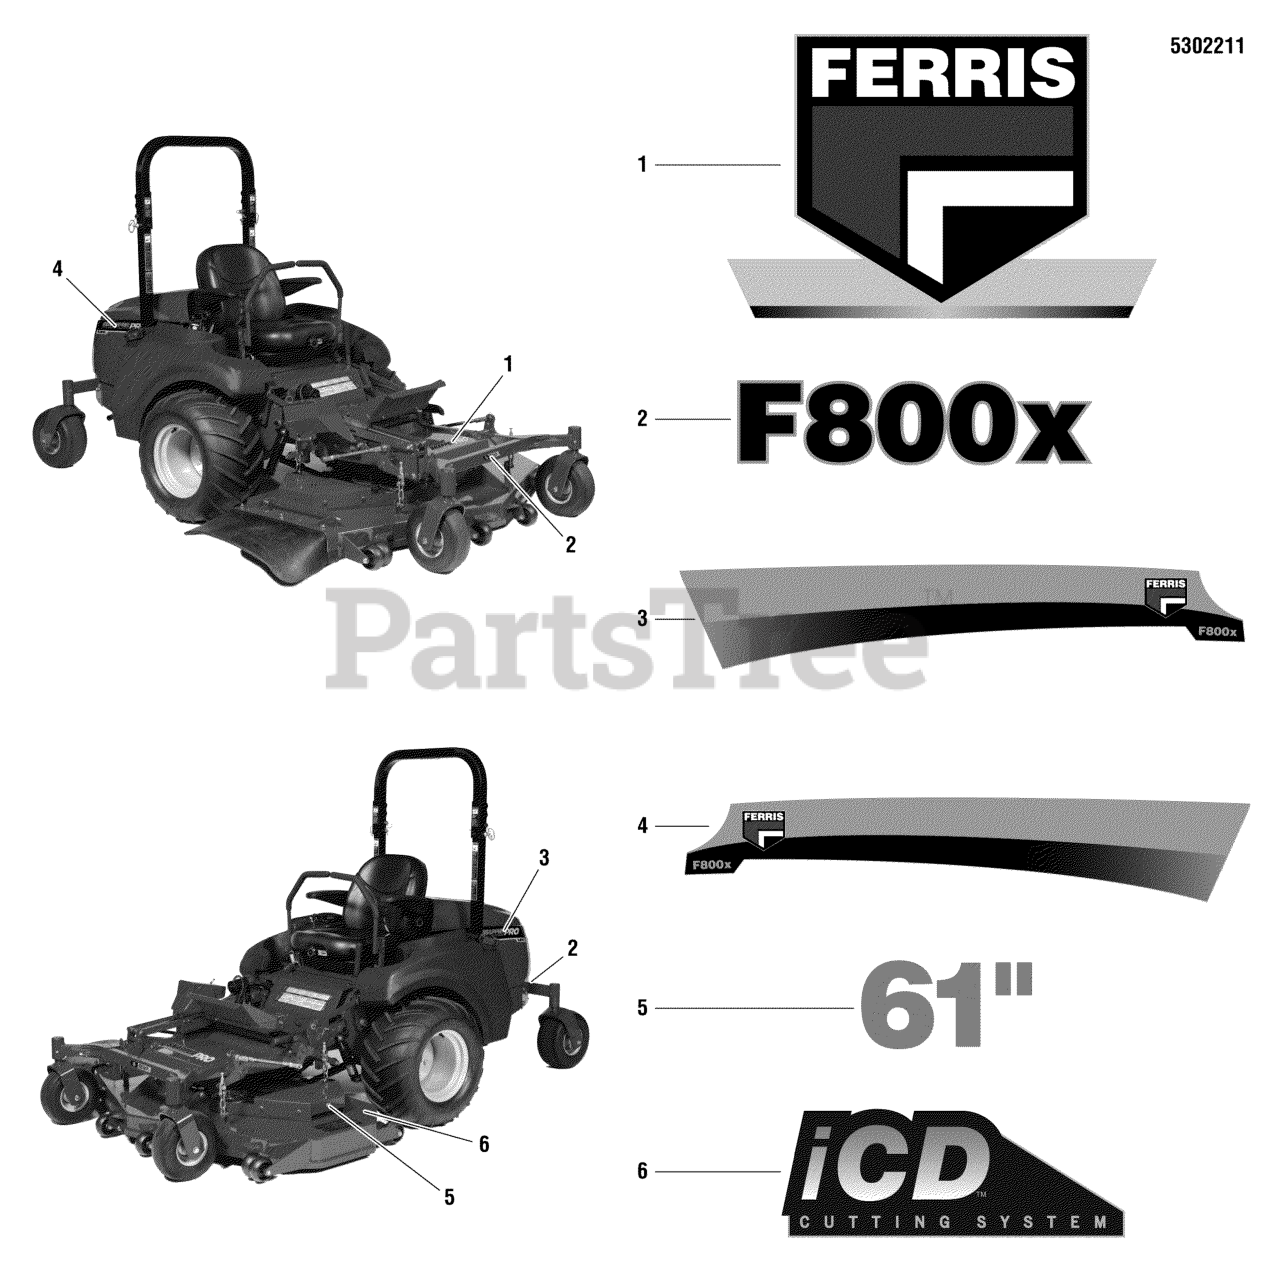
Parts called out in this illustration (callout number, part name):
1	DECAL, FERRIS, SHIELD
2	DECAL, F800X
3	DECAL, LH STRIPE, F800X
4	DECAL, RH STRIPE, F800X
5	DECAL, 61
6	DECAL, iCD CUTTING SYSTEM
